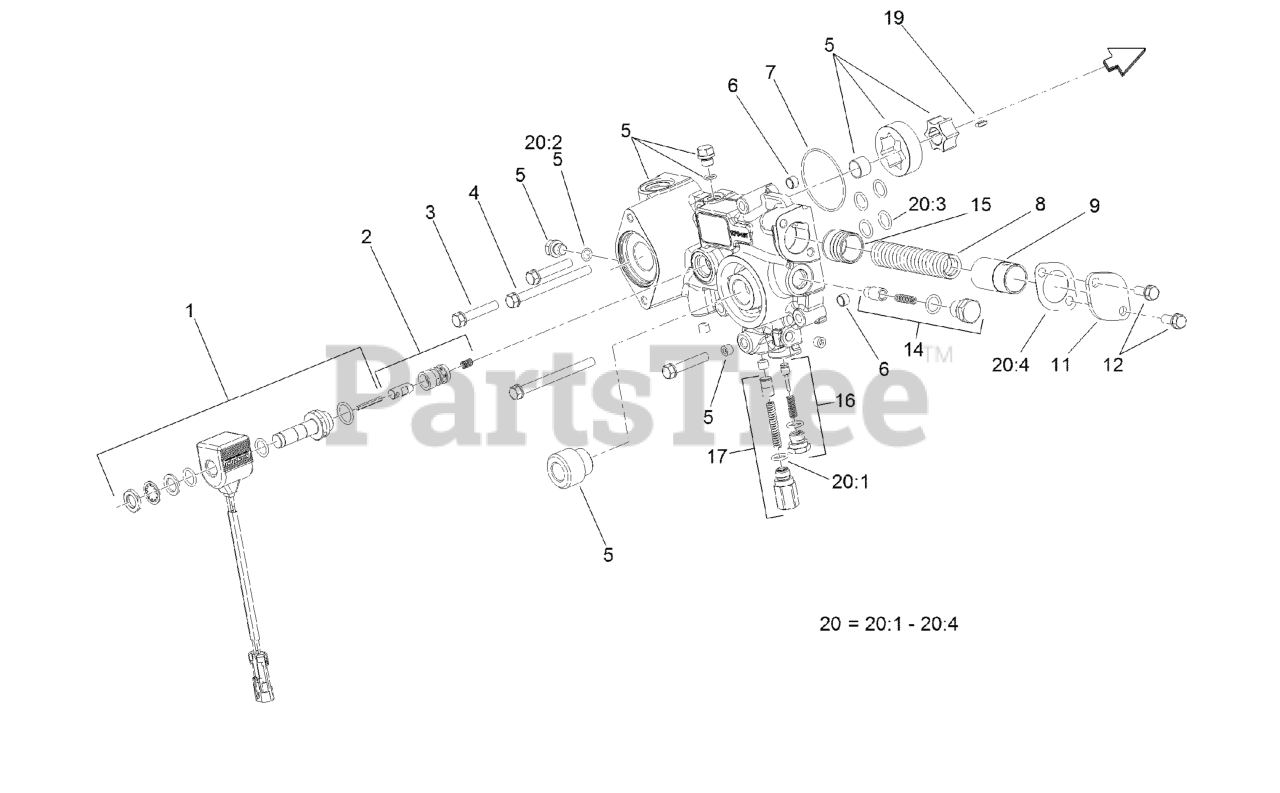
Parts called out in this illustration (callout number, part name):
1	SOLENOID ASM
2	SOLENOID VALVE ASM
5	PUMP BODY ASM
12	BOLT AND WASHER ASM
14	FILTER BYPASS VALVE ASM
16	CHARGE RELIEF VALVE ASM
17	PRESSURE VALVE ASM
20	CHARGE PUMP SEAL KIT
20:2	O RING-PLUG
20:3	Packing
